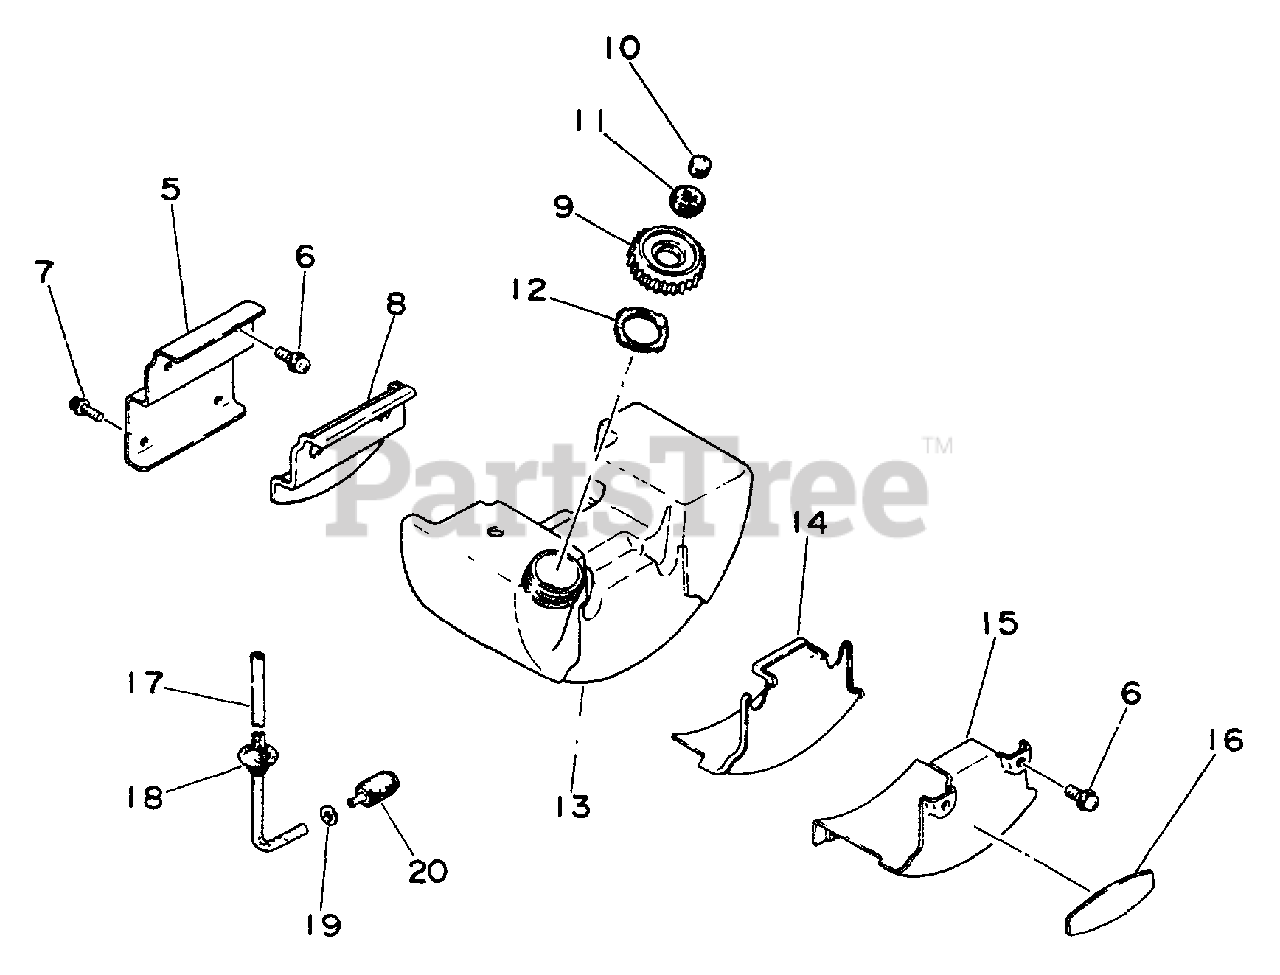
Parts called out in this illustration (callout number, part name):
5	BRACKET, FUEL TANK
6	SCREW - 5X14
7	SCREW - 4X14
8	CUSHION
9	CAP ASSY
12	GASKET, CAP
13	TANK, FUEL
15	BRACKET, FUEL TANK
16	LABEL - ECHO
17	FUEL PIPE KIT
19	WASHER - 5
20	FILTER, FUEL
